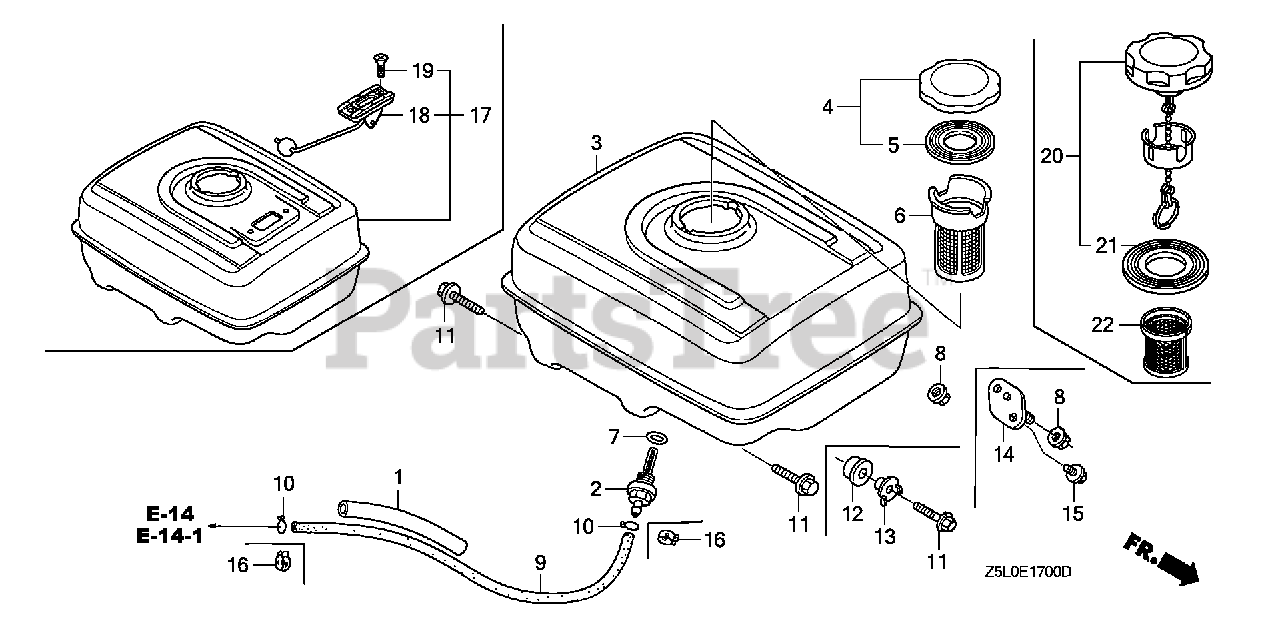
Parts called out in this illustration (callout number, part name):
1	RUBBER, SUPPORTER (107MM)
2	JOINT, FUEL TANK
3	TANK, FUEL *NH31* (MCKINLEY WHITE)
4	CAP, FUEL FILLER (CHROME PLATED)
5	GASKET, FUEL FILLER CAP (39X62X3) (TOUYOUSYA)
7	O-RING (13.5X1.5) (ARAI)
7	O-RING (14MM) (NOK)
8	NUT, FLANGE (8MM)
9	TUBE, FUEL (4.5X235) (FKM)
9	BULK HOSE, FUEL (4.5X3000) (4.5X235)
10	CLIP, TUBE (B8)
11	BOLT, FLANGE (8X25)
16	CLAMP, TUBE (D8)
20	CAP, FUEL FILLER (CHROME PLATED)
20	CAP, FUEL FILLER
21	GASKET, FUEL FILLER CAP (39X62X3) (RADICON)
21	GASKET, FUEL FILLER CAP (39X62X3)
